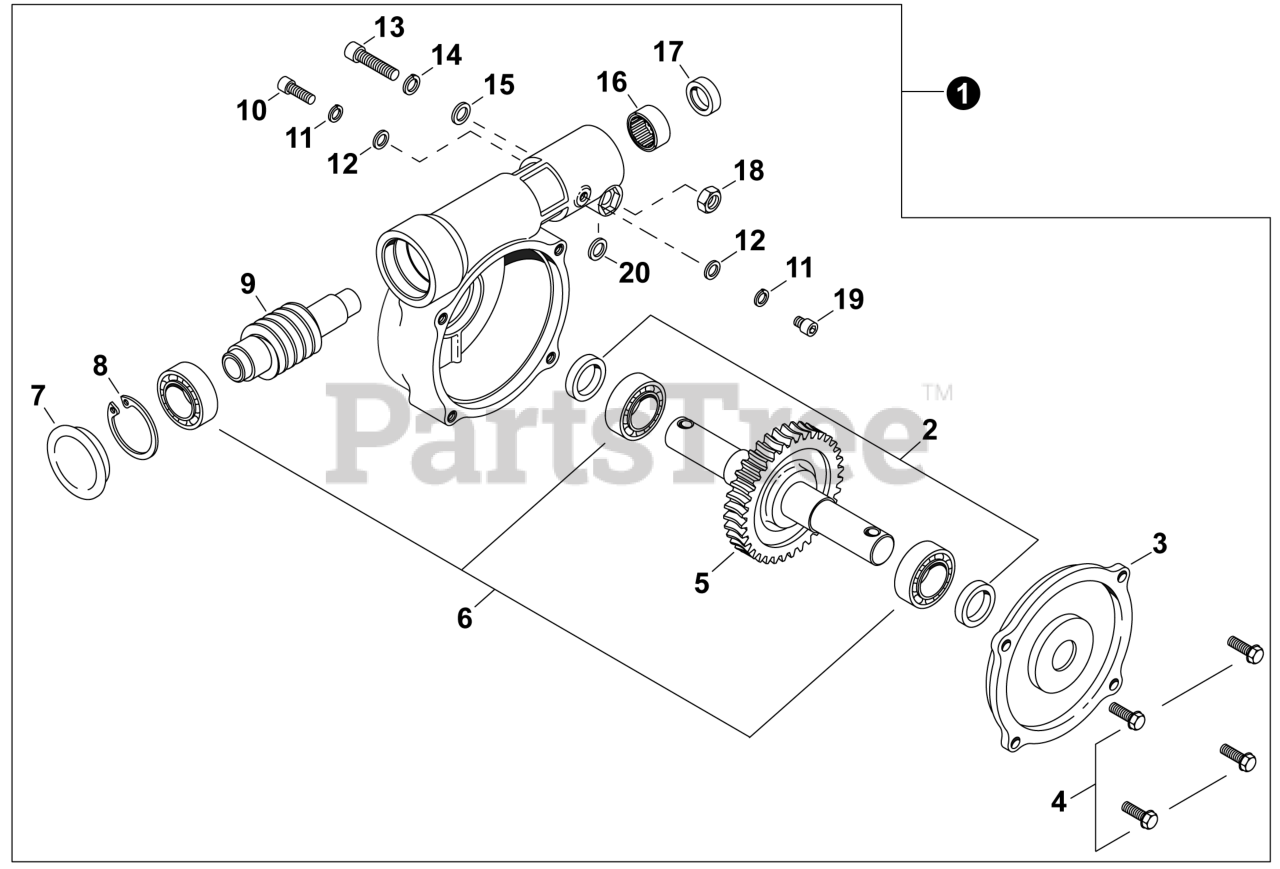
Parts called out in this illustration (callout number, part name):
1	GEAR CASE ASSY - 26MM
2	SEAL, OUTPUT SEG TC15-24-5-20
3	COVER, GEAR CASE
4	SCREW SELF-TAPPING 5x16
5	GEAR, DRIVE
6	BEARING, BALL PEER 6002
7	PLUG
8	RING, SNAP 34 MM
9	GEAR, WORM
10	BOLT 5x12
11	WASHER, SPRING 5
12	WASHER, FLAT 5.5x10x0.8
13	SCREW, SOCKET HEAD 6x30
14	WASHER, LOCK M6
15	WASHER M6
16	BEARING, NEEDLE SCE 107 1/2 NF R
17	SEAL, INPUT SCG TC-12-21-6
18	NUT M6
19	BOLT 5x8x0.80
20	WASHER M6
